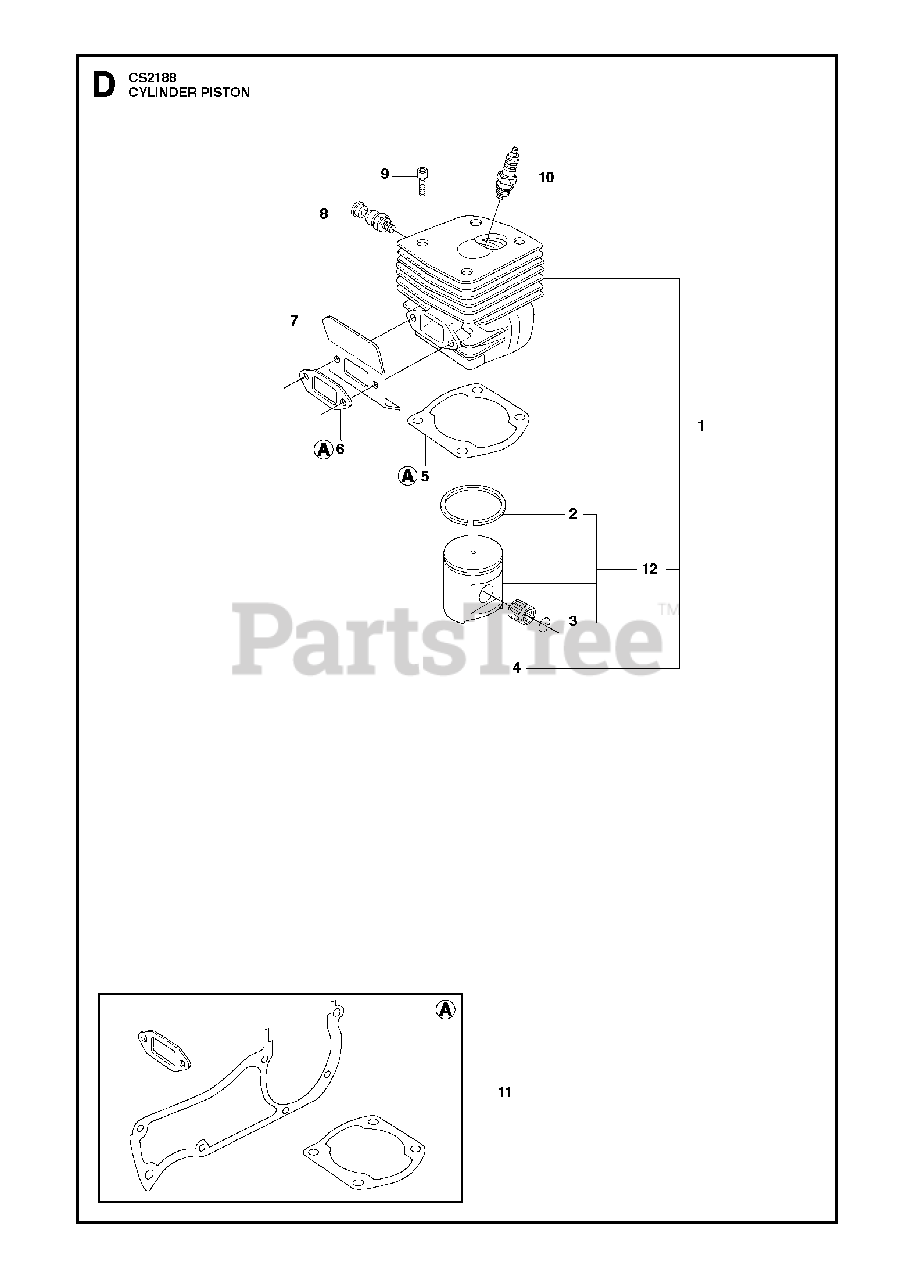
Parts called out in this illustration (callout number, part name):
1	CYLINDER ASSY
2	PISTON RING
3	CLIP
4	SUPPORT BUSHING
5	GASKET
6	GASKET
7	DEFLECTOR
8	DECOMPRESSION VALVE
9	SCREW MC6S 5X25
10	SPARK PLUG RCJ7Y
11	GASKET SET
12	PISTON ASSY
